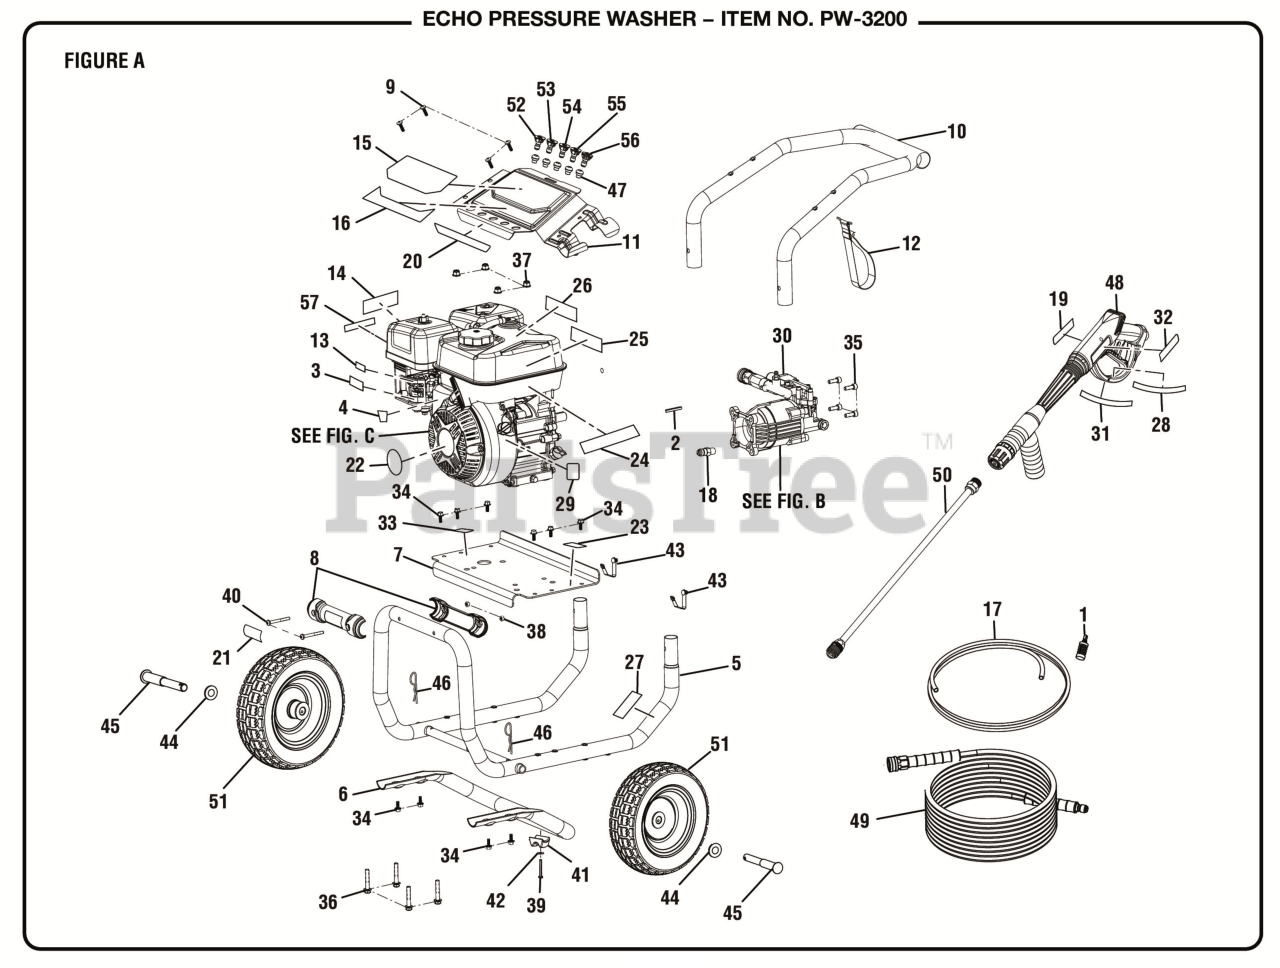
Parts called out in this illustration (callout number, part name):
1	PREFILTER
3	LABEL, FUEL VALVE
4	LABEL, CHOKE/FUEL CALLOUT
5	FRAME, MAIN
6	FRAME, REAR
7	PLATE, ENGINE
8	GRIP, FRONT HANDLE
9	SCREW, PHILLIPS HEAD
10	FRAME, HANDLE
12	PLATE, CHAIN GUARD
13	LABEL, CHOKE
14	LABEL, HOT SURFACE
15	LABEL, LOGO
16	LABEL, PERFORMANCE
17	HOSE, SIPHON
18	VALVE, THERMAL RELEASE
19	LABEL, TRIGGER HANDLE LOGO
20	LABEL, NOZZLE
21	LABEL, FRONT GRIP LOGO
22	LABEL, RECOIL
23	LABEL, LOW OIL SHUTDOWN
24	LABEL, COMBUSTION WARNING
25	LABEL, DANGER
26	LABEL, E85
27	LABEL, INQUIRIES
28	LABEL, TRIG HNDL(FR/SP)
29	LABEL, ENGINE SWITCH
30	PUMP, PW-3200
31	LABEL, TRIGGER HANDLE RATING
32	LABEL, TRIG HNDL (ENG)
33	LABEL, DATA WARNINGS
34	BOLT, FLANGE
35	BOLT, SOCKET HEAD
36	BOLT, FLANGE HEAD
37	NUT, NYLOC FLANGE
38	NUT, NYLOC
39	SCREW, TORX PAN HEAD
41	RUBBER FOOT
43	CLIP, HANDLE SPRING
46	PIN, HITCH
47	GROMMETS
48	CATCHER, CHAIN
49	HOSE, HIGH PRESSURE
50	WAND, SPRAY
52	NOZZLE, 0 DEGREE
53	NOZZLE, 15 DEGREE
54	NOZZLE, 25 DEGREE
55	NOZZLE, 40 DEGREE
56	NOZZLE, SOAP
57	LABEL, EMC
